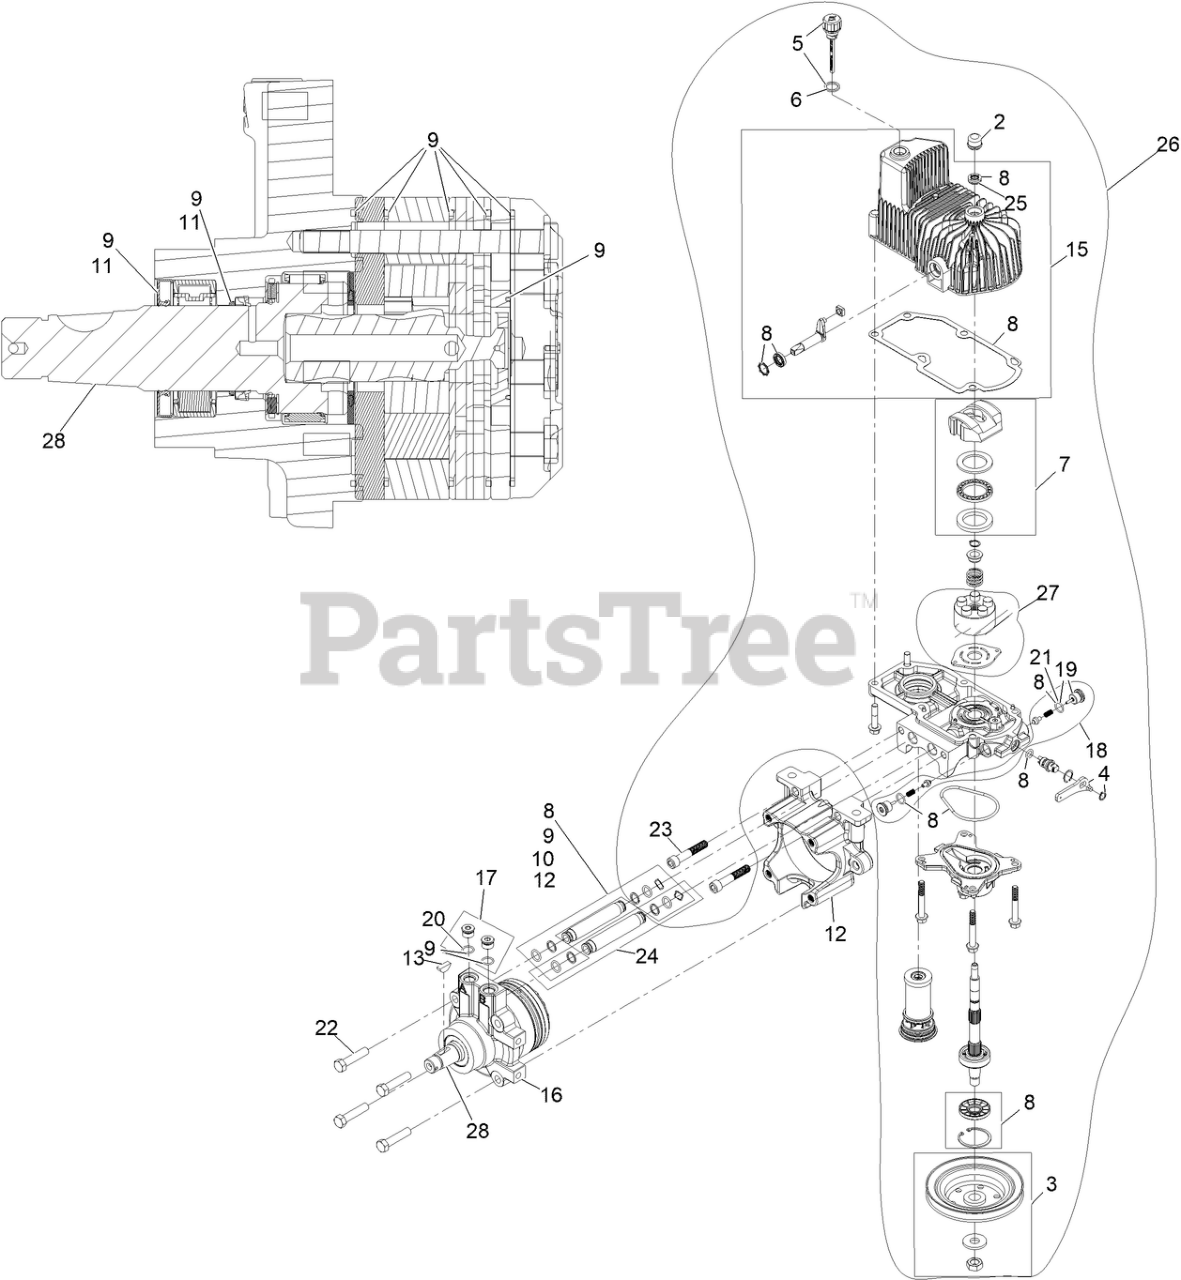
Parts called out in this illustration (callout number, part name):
2	COVER-SHAFT, HYDRO
3	PULLEY KIT
4	HANDLE-BYPASS VALVE, HYDRO
5	DIPSTICK-HYDRO W/GASKET
6	GASKET-DIPSTICK, HYDRO
7	SWASH BLOCK KIT
8	Kit, Pump Seal
9	MOTOR SEAL KIT
10	TUBE SEAL KIT
11	OUTPUT SHAFT SEAL KIT
12	NOSE CUP-UHT
13	KEY-WOODRUFF
15	Kit, Housing-Hydro LH
16	MOTOR-HYDRAULIC LH 240CC
17	MAGNETIC PLUGS SERVICE KIT
18	ASM, CHECK VALVE
19	PLUG-CHECK (W/O-RING)
21	O-RING-CHECK VALVE
22	SCREW HH
23	SCREW-HSH
24	HYDRAULIC TUBE KIT
25	SEAL-FAN DRIVE
26	KIT, PUMP SECTION 12CC LH NO FAN
27	Kit - 12Cc Port Plate,Rotate Grp
28	OUTPUT SHAFT- TL UHT MOTOR
